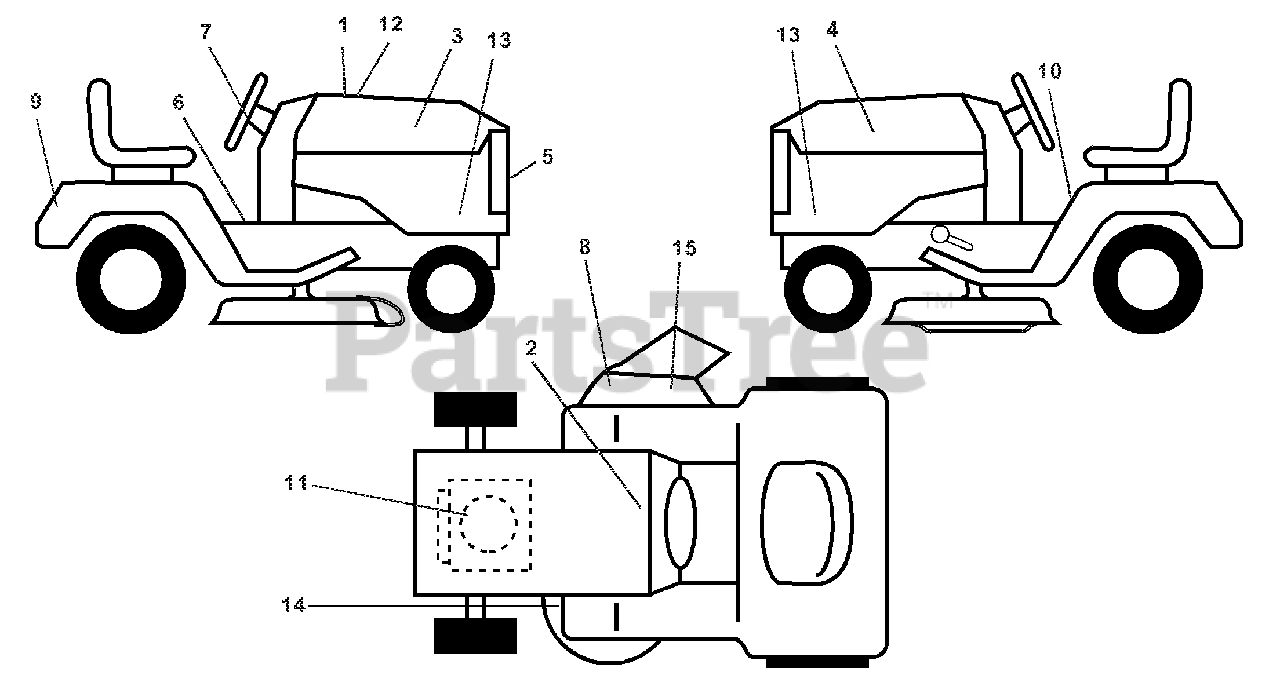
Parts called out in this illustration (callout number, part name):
1	Decal Hood Cust. Resp.
2	Decal Battery
3	Decal Hood RH
4	Decal Hood LH
5	Decal Grille
6	Decal Fender Oper
7	Decal Wheel Steering
8	Decal Warning
9	Decal Fender Husq
10	Decal Fender Danger E/F
11	Decal Engine
12	Decal Hood
13	Decal Hoodsides Kawa VTWN
14	Decal V-Belt Schematic
15	Decal Deck "B" 42"
